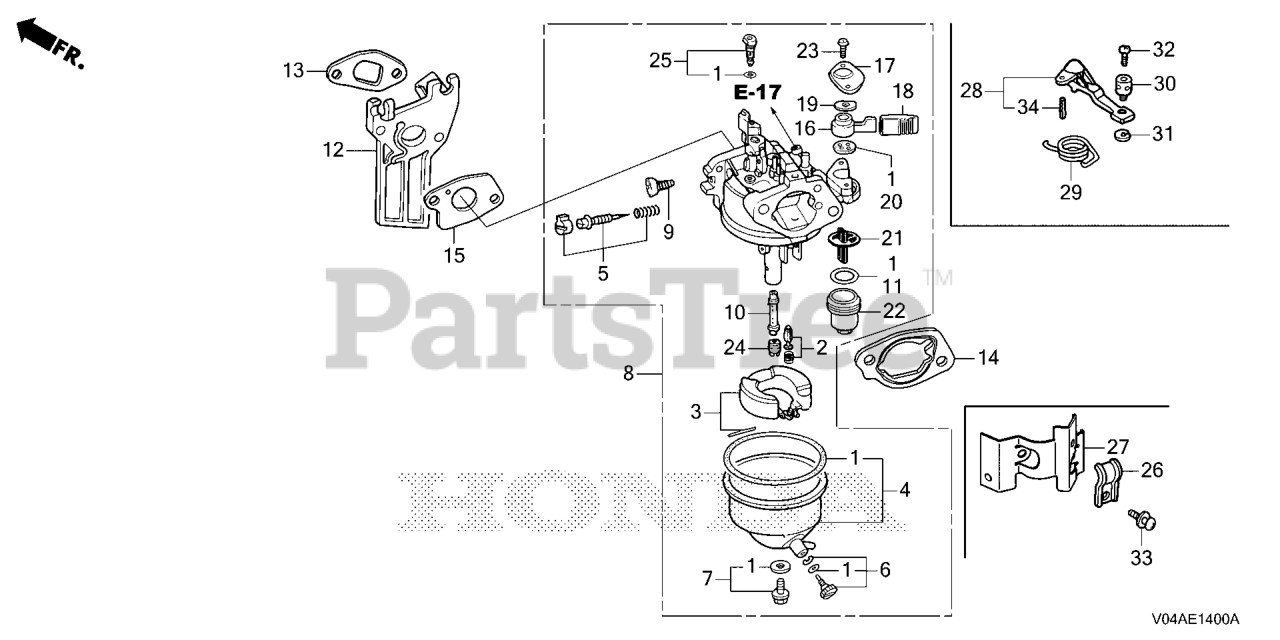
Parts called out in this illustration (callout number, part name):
1	GASKET SET (CARBURETOR NO.)
2	VALVE SET, FLOAT (CARBURETOR NO.) (SEAT NOT INCLUDED)
3	FLOAT SET
4	CHAMBER, FLOAT
5	SCREW SET (Honda Code 4219879). (CARBURETOR NO.)
5	SCREW SET (CARBURETOR NO.)
6	SCREW SET, DRAIN (CARBURETOR NO.)
7	SCREW SET (CARBURETOR NO.)
8	CARBURETOR ASSY. (BEA3D A)
8	CARBURETOR ASSY. (BEA3W A)
9	SCREW, THROTTLE STOP
10	NOZZLE, MAIN
10	NOZZLE, MAIN (CARBURETOR NO.)
11	GASKET, FUEL STRAINER CUP
12	INSULATOR, CARBURETOR
13	GASKET, INSULATOR
14	SPACER, CARBURETOR
15	GASKET, CARBURETOR
16	LEVER, VALVE
17	PLATE, LEVER SETTING (CARBURETOR NO.)
18	CAP, LEVER
19	SPRING, PETCOCK LEVER (CARBURETOR NO.)
20	GASKET, VALVE
21	FILTER, CUP (CARBURETOR NO.)
22	CUP, FUEL STRAINER
23	SCREW, PAN (3X6)
24	JET, MAIN (#72) (CARBURETOR NO.)
24	JET, MAIN (#75) (CARBURETOR NO.)
24	JET, MAIN (#70)
24	JET, MAIN (#78) (CARBURETOR NO.)
25	JET SET, PILOT (#45)
25	JET SET, PILOT (#38)
26	HOLDER, CONTROL CABLE
27	STAY, CHOKE CONTROL
28	LEVER, CHOKE (REMOTE)
29	SPRING, RETURN
30	HOLDER, CABLE
31	CIRCLIP (5MM) Use from Engine SN 2327377.
32	SCREW, PAN (4X8)
33	SCREW-WASHER (5X10) Use up to Frame SN 1382074.
34	PIN, SPRING (2X12)
